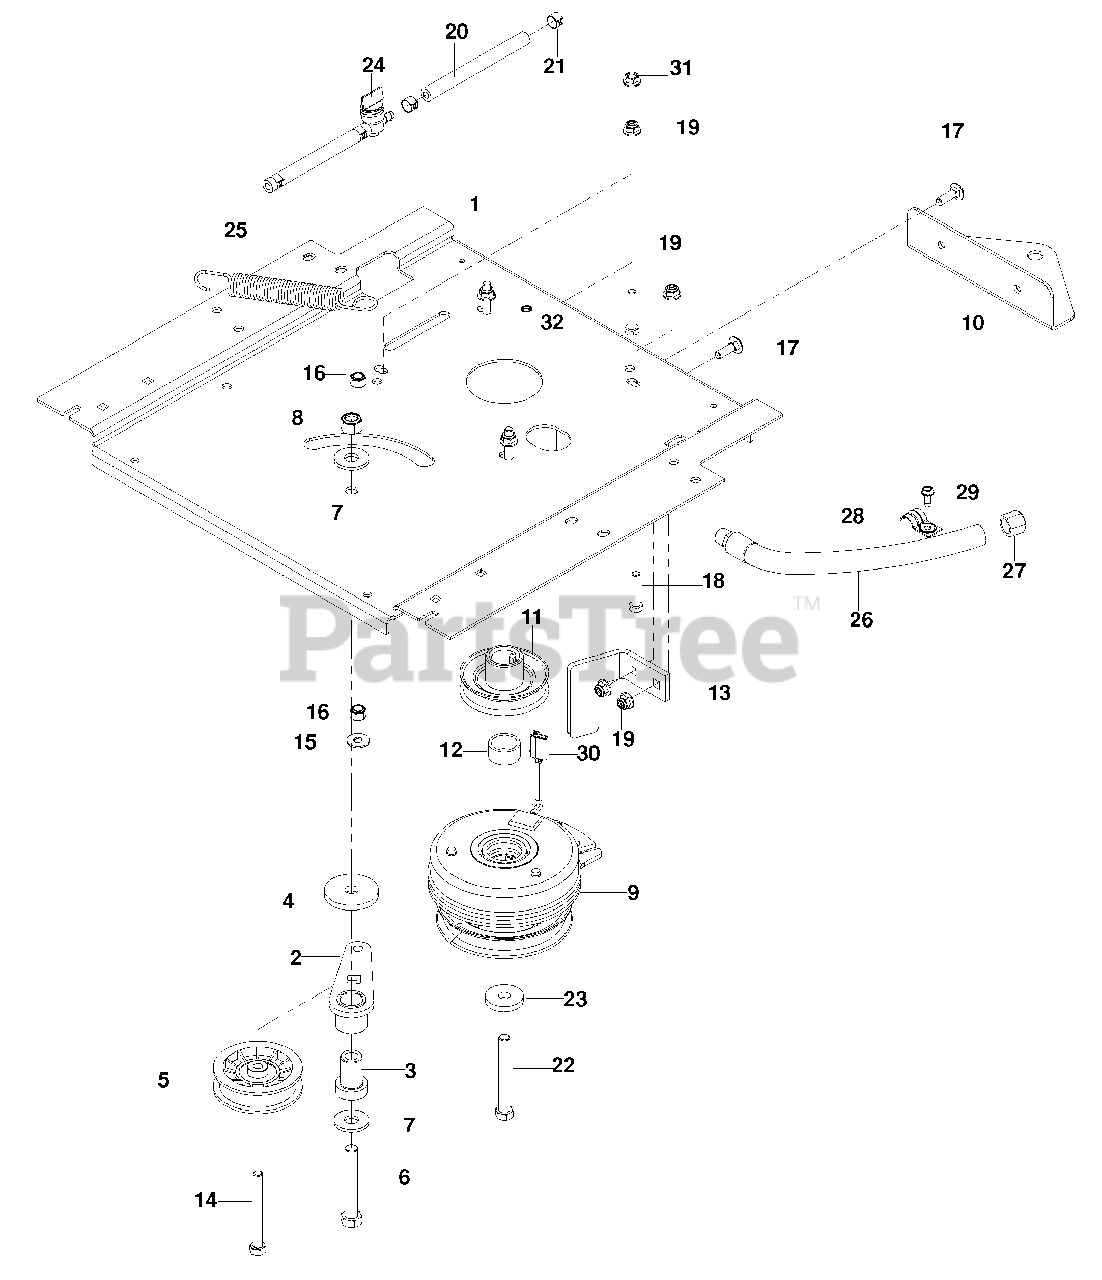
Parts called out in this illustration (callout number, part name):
1	PLATE, ENGINE
2	ARM, IDLER
3	SPINDLE, IDLER
4	WASHER, HEAVY
5	PULLEY, IDLER
6	HCS 1/2-13 x 3 1/4
7	WASHER 1/2 FLT
8	NUT 1/2-13 HEX NYLOC
11	PULLEY, ENGINE
13	STOP, CLUTCH
14	HCS 3/8-16 x 3 1/2 TPBLT
15	WASHER 5/16 STD FLT
16	NUT 3/8-16 HEX NYLOC
17	RHSNB 5/16-18 x 1
18	HCS 5/16-18 x 1 1/2
19	NUT 5/16-18 FLANGE NYLOC
20	FUEL LINE 5"
21	CLAMP, HOSE
22	HCS 7/16-20 x 3 1/2
23	WASHER, CLUTCH
24	VALVE, FUEL
25	SPRING, DECK DRIVE
26	HOSE, DRAIN
29	SCREW 1/4-20 x 5/8 SLF TAP
30	HARNESS, CLUTCH
31	NUT 5/16-18 WHIZLK
32	HCS 5/16-18 x 1 3/4
